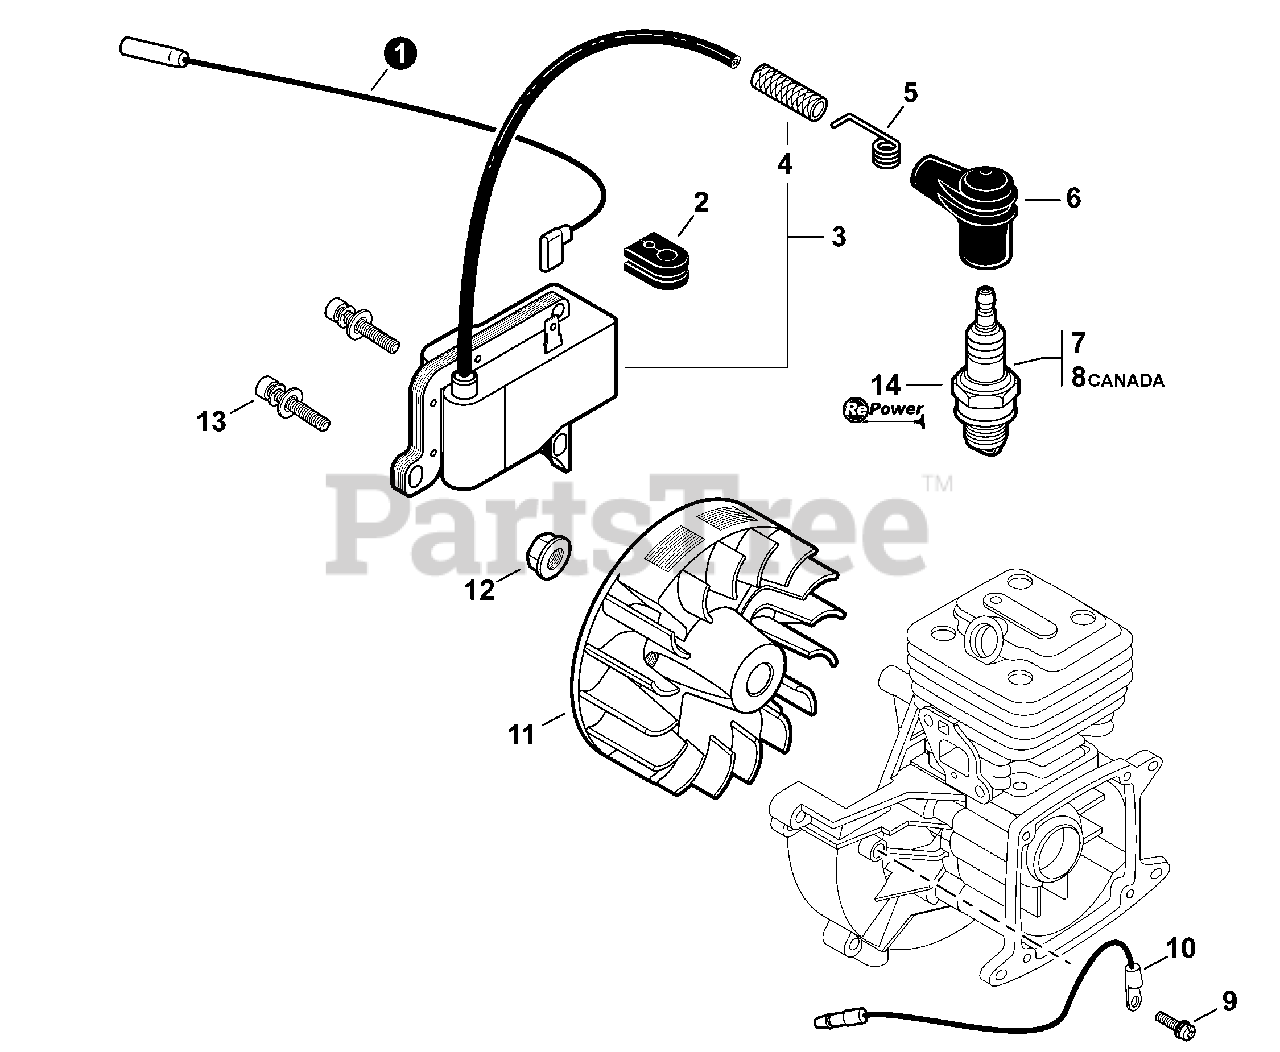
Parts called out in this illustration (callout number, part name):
1	LEAD - IGNITION 145mm
3	COIL SET, IGNITION
4	TUBE, INSULATOR
5	TERMINAL, SPARK PLUG
6	CAP, SPARK PLUG
7	SPARK PLUG - BPM8Y
8	SPARK PLUG - BPMR8Y
9	SCREW 5×10
10	LEAD - GROUND
11	FLYWHEEL
12	NUT, FLANGE M8
13	BOLT 5×16
14	TUNE-UP KIT - REPOWER
